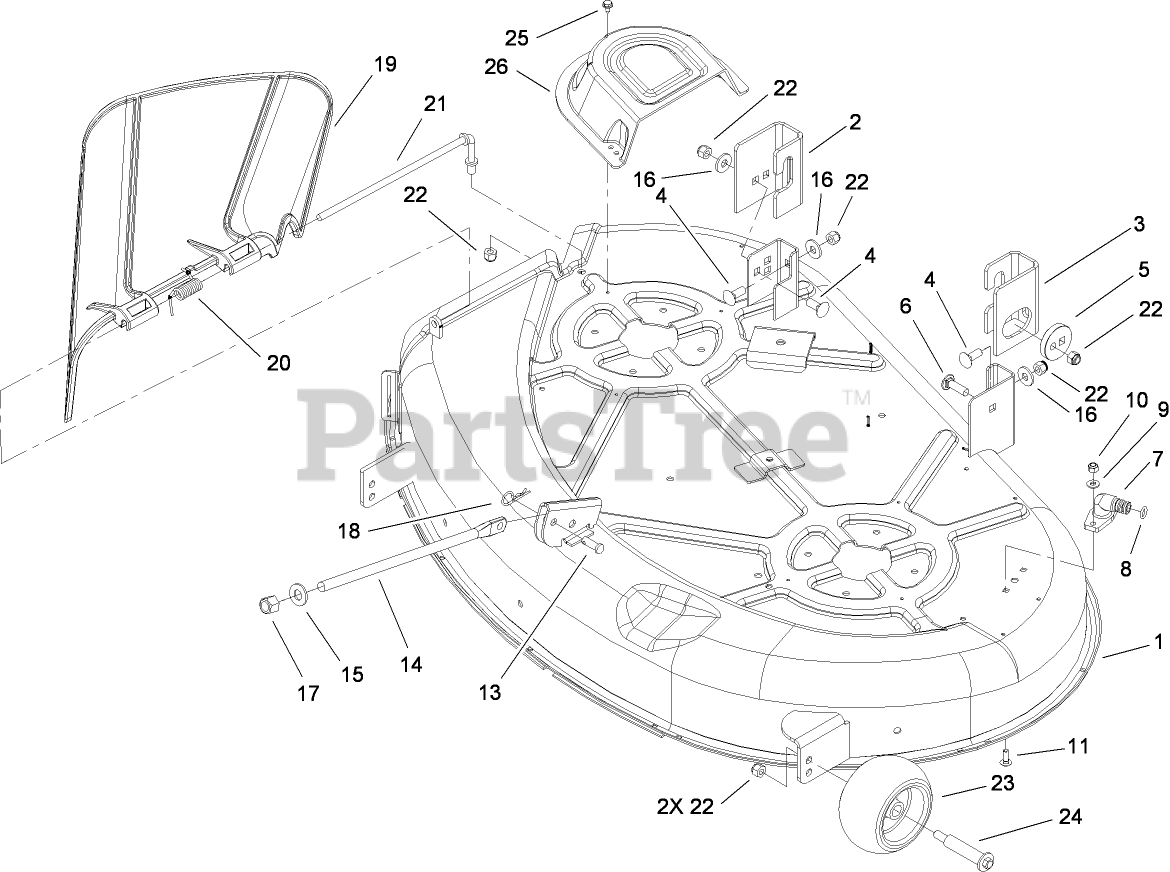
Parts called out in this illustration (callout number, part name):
2	BRACKET-HANGER, RIGHT REAR
3	BRACKET-HANGER, LEFT REAR
4	BOLT-CARR
5	ECCENTRIC
6	SCREW-CARR
8	O-RING
9	WASHER-FLAT
10	NUT-LOCK, NI
11	BOLT-CARR
13	PIN-CLEVIS
14	ROD-LIFT
15	WASHER-THRUST
16	WASHER-HARDENED
17	NUT-LOCK, NI
18	PIN-HAIR
19	DEFLECTOR
20	SPRING-TORSION
21	ROD-PIVOT
22	NUT-LOCK, NI
23	ROLLER-SCALP, ANTI
24	BOLT-SHOULDER
25	SCREW-HWHTF
26	COVER-BELT
